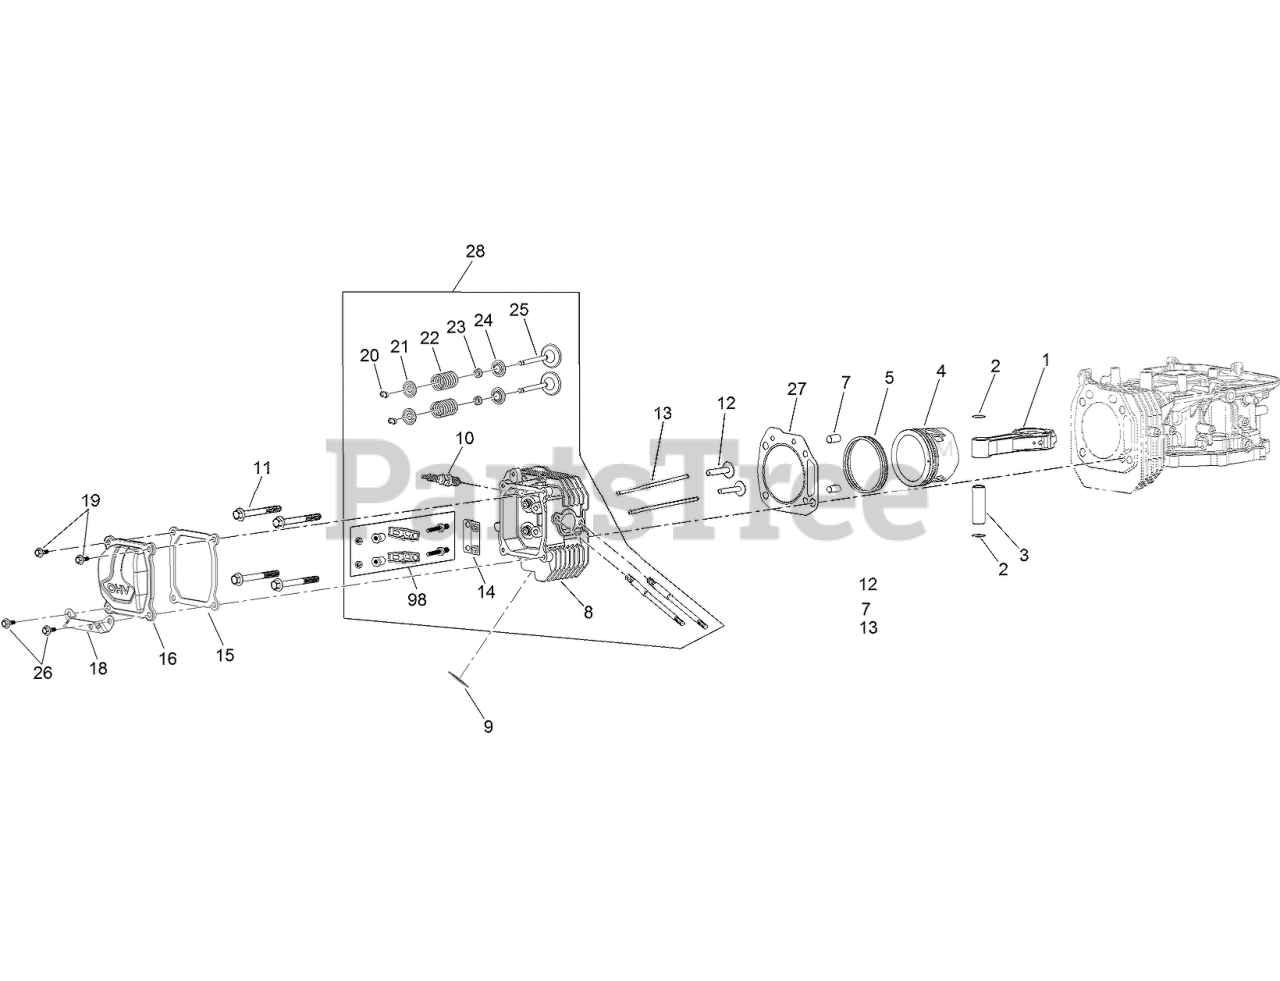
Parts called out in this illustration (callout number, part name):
1	CONNECTING ROD ASM
2	RING-RETAINING, PISTON PIN
3	PIN-PISTON
4	PISTON
5	RING SET
7	PIN-DOWEL
8	HEAD-CYLINDER
9	GASKET-EXHAUST
10	PLUG-SPARK
11	SCREW-HHF
12	LIFTER-VALVE
13	ROD-PUSH
14	PLATE-GUIDE, PUSH ROD
15	GASKET-COVER, VALVE
16	COVER-VALVE
18	BRACKET-MUFFLER
19	SCREW-SHOULDER, HHF
20	KEEPER-VALVE
21	RETAINER-SPRING, VALVE
22	SPRING-VALVE
23	SEAL-STEM, VALVE
24	SEAT-SPRING, VALVE
25	VALVE SET
26	SCREW-SHOULDER, HHF
27	GASKET-CYCLINDER
28	COMPLETE HEAD ASM
98	ROCKER ARM KIT
